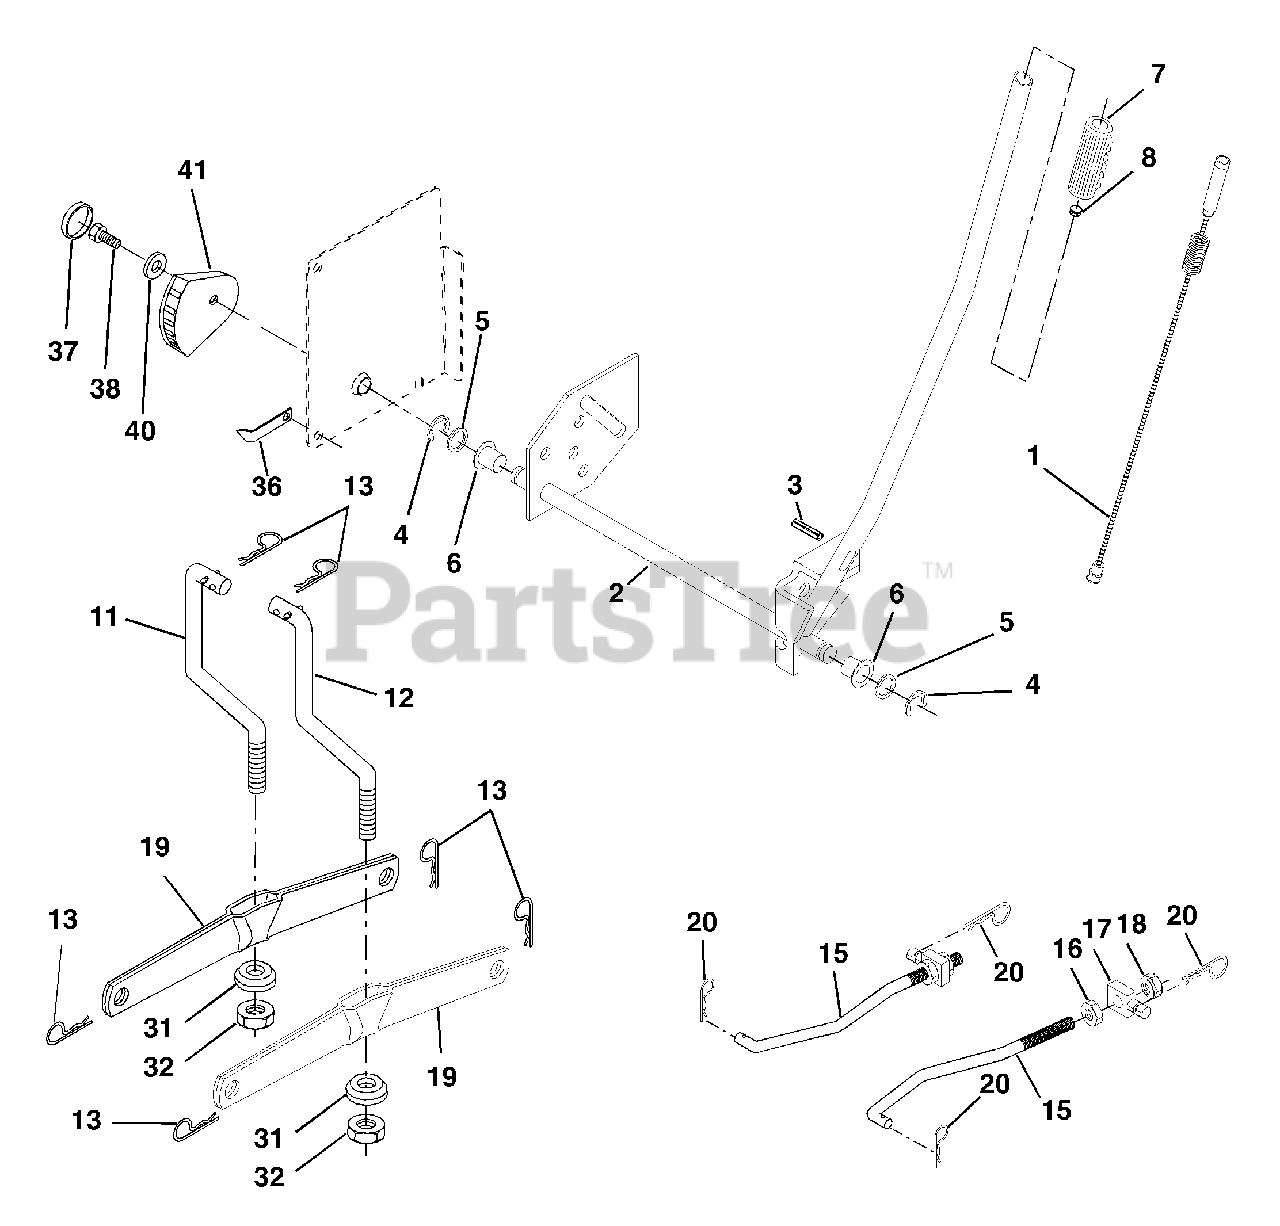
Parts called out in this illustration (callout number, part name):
1	Wire Asm Inner/Sprg W/plunger LT
2	Shaft Asm Lift RH w/Inf
3	Pin Groove 1 500 Zinc
4	E Ring #5133-62
5	Washer 21/32 X 1 X 21 Ga
6	Bearing Nylon Blk 629 Id
7	Grip Handle
8	Button Plunger Yellow
11	Link Lift LH Fixed Length
12	Link Lift RH Fixed Length
13	Retainer Spring
15	Link Front
16	Nut Jam Hex 1/2-13 Unc
17	Trunnion
18	Nut Lock w/Wsh 1/2-13 Unc
19	Arm Suspension Rear
20	Retainer Spring
31	Bearing Pvt Lift
32	Nut Crownlock 3/8 - 24
36	Pointer Height Indicator
37	Plug Hole Blk 1.485/1.515 Dia.
38	Screw Thdrol 5/16-18 x 1
40	Washer 11/32 x 1-1/2 10 Ga.
41	Indicator Height STLT
